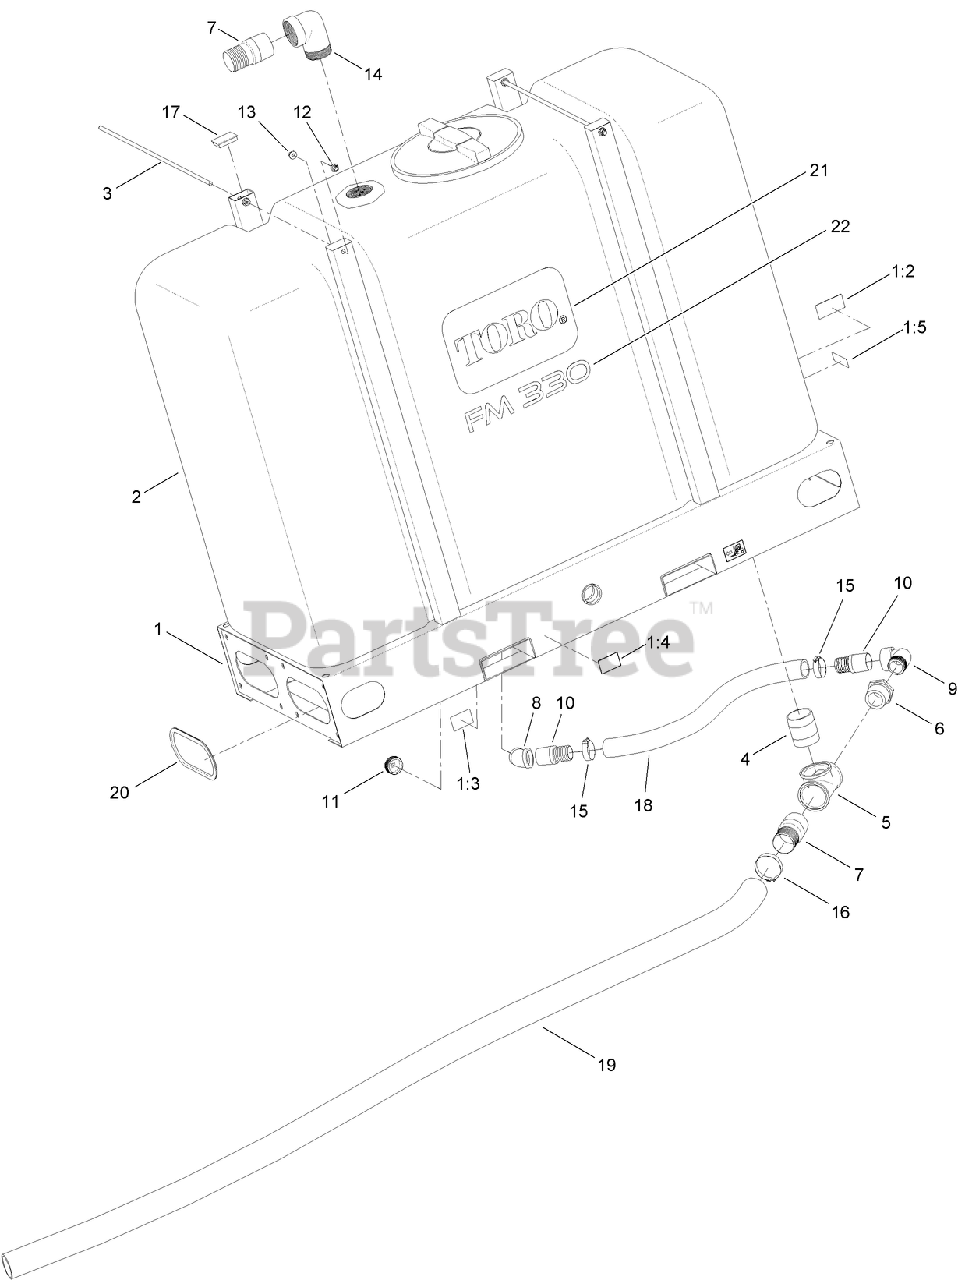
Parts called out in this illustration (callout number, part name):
1	MIX TANK FRAME ASM
1:2	DECAL-WARNING, MIXER
1:3	DECAL-DRAIN
1:4	DECAL-FORKLIFT
1:5	DECAL-GROUND ROD
2	500 GALLON MIX TANK ASM
3	BAR-THREADED, STEEL
4	NIPPLE-PIPE
5	TEE-PIPE
6	BUSHING-PIPE
7	NIPPLE-COMBINATION
8	ELBOW-PIPE-45
9	ELBOW-PIPE, STREET, 90 DEG
10	NIPPLE-COMBINATION
11	PLUG-PIPE, SQUARE HEAD
12	NUT-LOCK
13	NUT-HHF
14	ELBOW-PIPE, 45 DEG
15	CLAMP-HOSE, T-BOLT
16	CLAMP-T BOLT
18	HOSE-SUCTION, WATER
19	HOSE-SUCTION, WATER
20	TRIM-FRAME, MIX TANK
